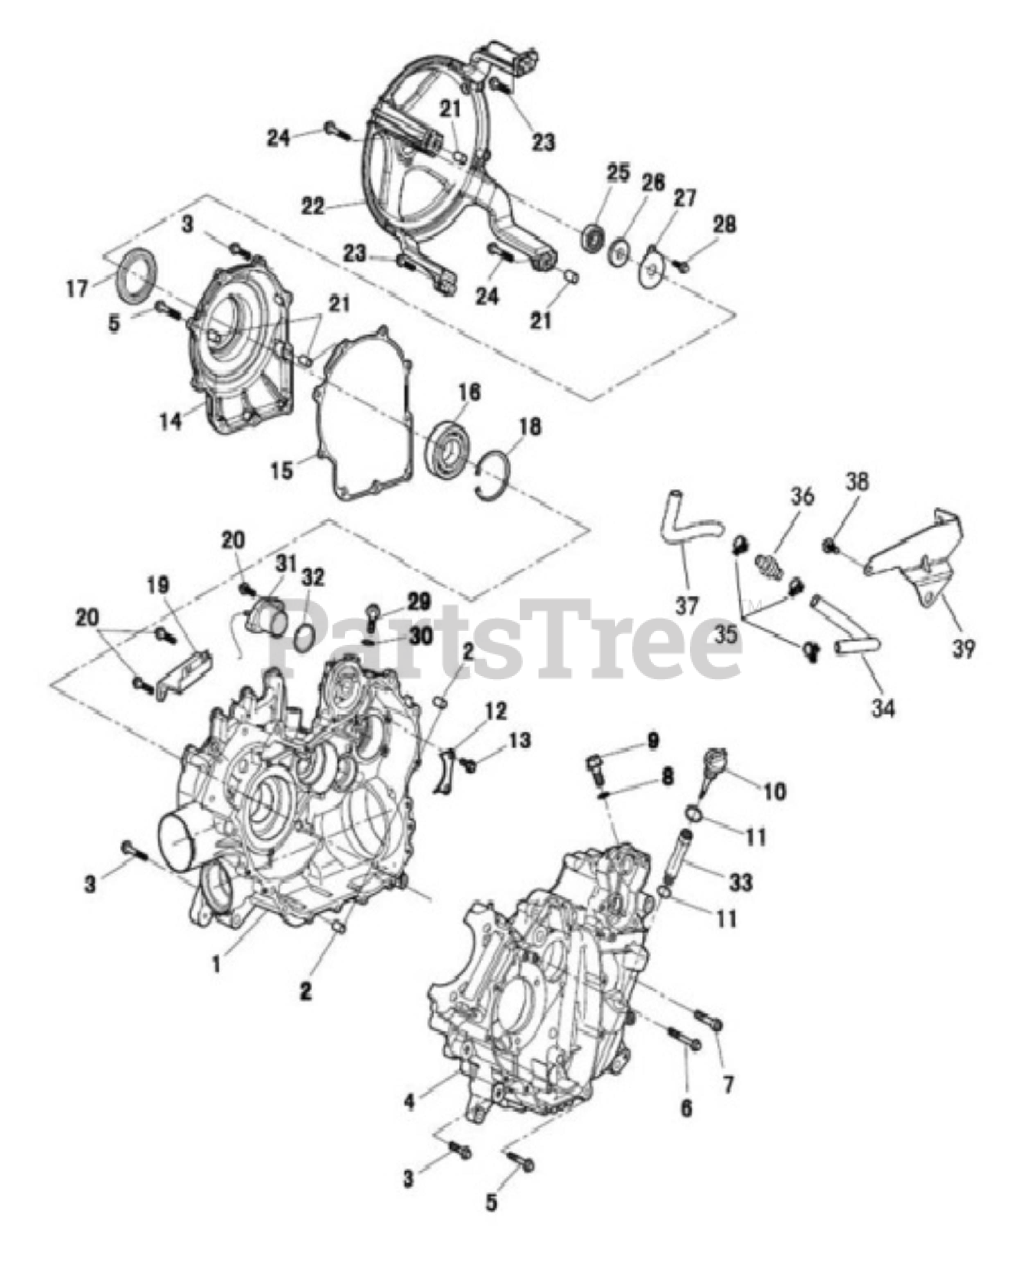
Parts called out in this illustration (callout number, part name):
1	Right Crankcase Assy
2	Pin,Dowel 9x12x16
3	Hex flange bolts M6x30
4	Left Crankcase Assy
5	Hex flange bolts M6x40
6	Hex flange bolts M6x85
7	Hex head cap screw M8x40
8	Aluminum Washer 14x20x1.5
9	Hex flange Screw Plug M14x1.5x16
10	Plug,Oil Level
11	O-Ring 18x3.5
12	Press Plate,Main Shaft Bearing
13	Hex flange bolts M6x16
14	Bearing Block,outer cover
15	Gasket,Bearing Block
16	Bearing 16010
17	Oil Seal 35x65x9
18	Circlip for hole 80
19	STRAP CVT VENT-PIPE PLATED
20	Hex head bolt & plain washer M6x16
21	Pin,Dowel 10x16
22	Shield Bracket,Clutch
23	Hex flange bolts M6x32
24	Hex flange bolts M6x40
25	BEARING 62012Z
26	Oil Seal 12x32x6
27	Press Plate,Bracket oil seal
28	Hex flange bolts M6x12
29	Hex flange bolts M10x1.25x16
30	Copper Washer 10x16x1
31	Sensor,Gear Indicator
32	O-Ring 29.6x2.4
33	Guiding Tube,Oil Level
34	ExHAUST GAS RECOVERY TUBEIII
35	SPRING CLAMP
36	NON PRESSURE CHECK VALVE
37	ExHAUST GAS RECOVERY TUBE
38	Hex flange bolts M6x30
39	AIR CLEANER STRAP - PLATED
